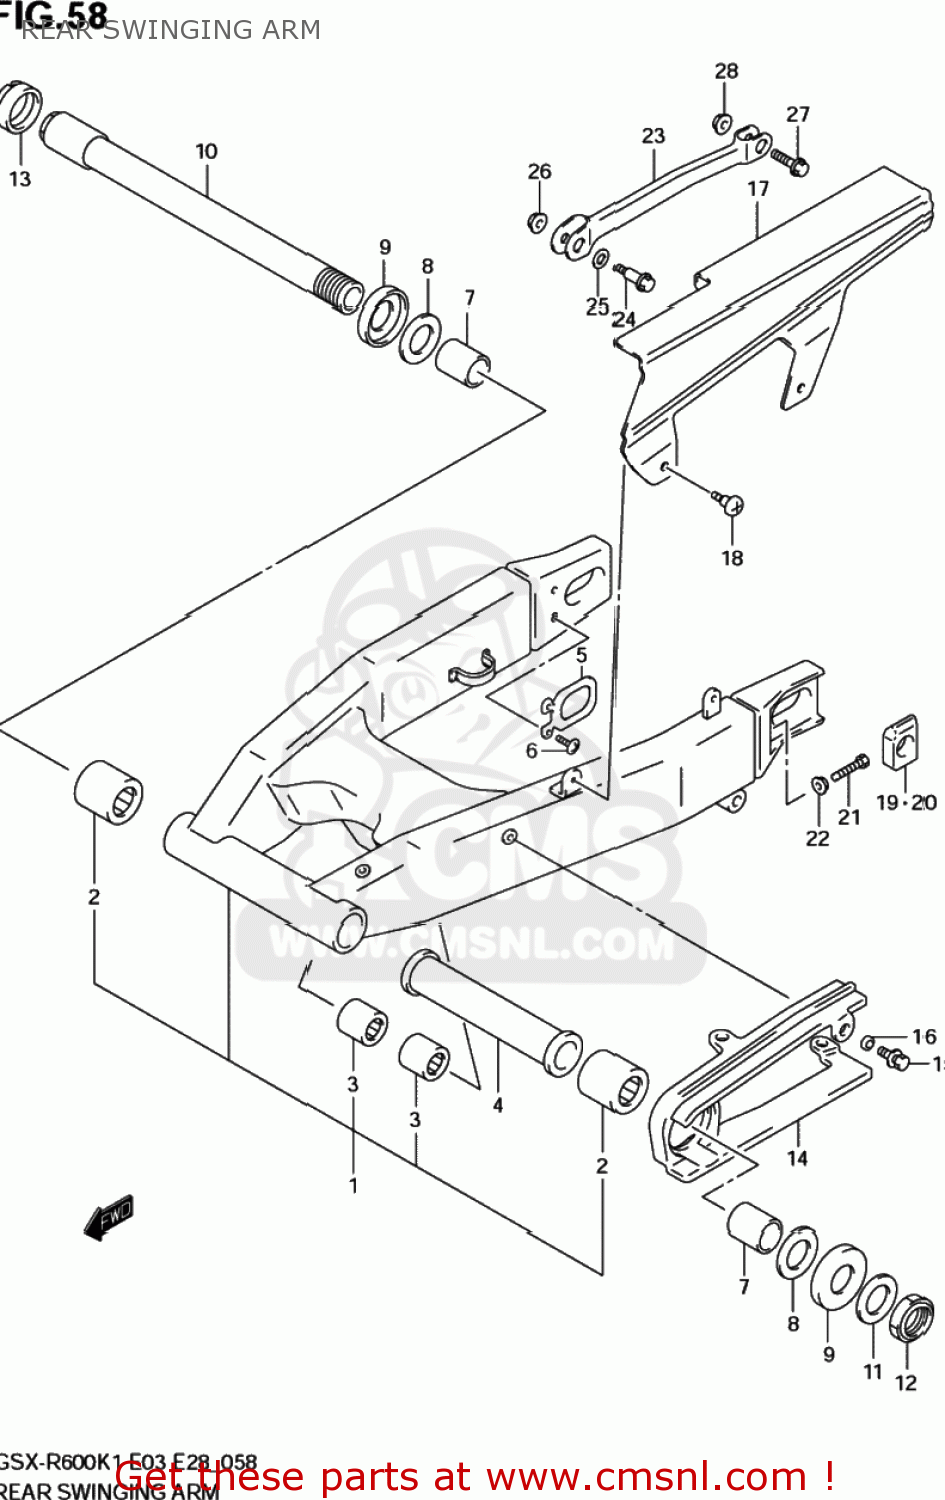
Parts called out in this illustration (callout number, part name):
1	SWINGINGARM ASSY,RR
2	BEARING(30X40X25)
3	BEARING(17X24X20)
4	SPACER,REAR SWING PIVOT,CENTER
5	PLATE,RR SWING ARM BRKT
6	SCREW
7	SPACER,REAR SWING ARM PIVOT
8	WASHER
9	DUST SEAL,RR SWGARM PIVOT
10	SHAFT,RR SWINGINGARM PIVOT
11	WASHER(25.2X42X3.2)
12	NUT
13	NUT,RR SWGARM PIVOT BOLT
14	BUFFER,CHAIN TOUCH DEFENSE
15	BOLT(6X20)
16	SPACER(6.5X9X5)
17	CASE,CHAIN
18	SCREW(6X16)
19	ADJUSTER,CHAIN,R
20	ADJUSTER,CHAIN,L
21	BOLT(8X50)
22	NUT
23	TORQUELINK,RR
24	BOLT(8X35.5)
25	WASHER(12.5X20X1)
26	NUT
27	BOLT(10X37)
28	NUT
